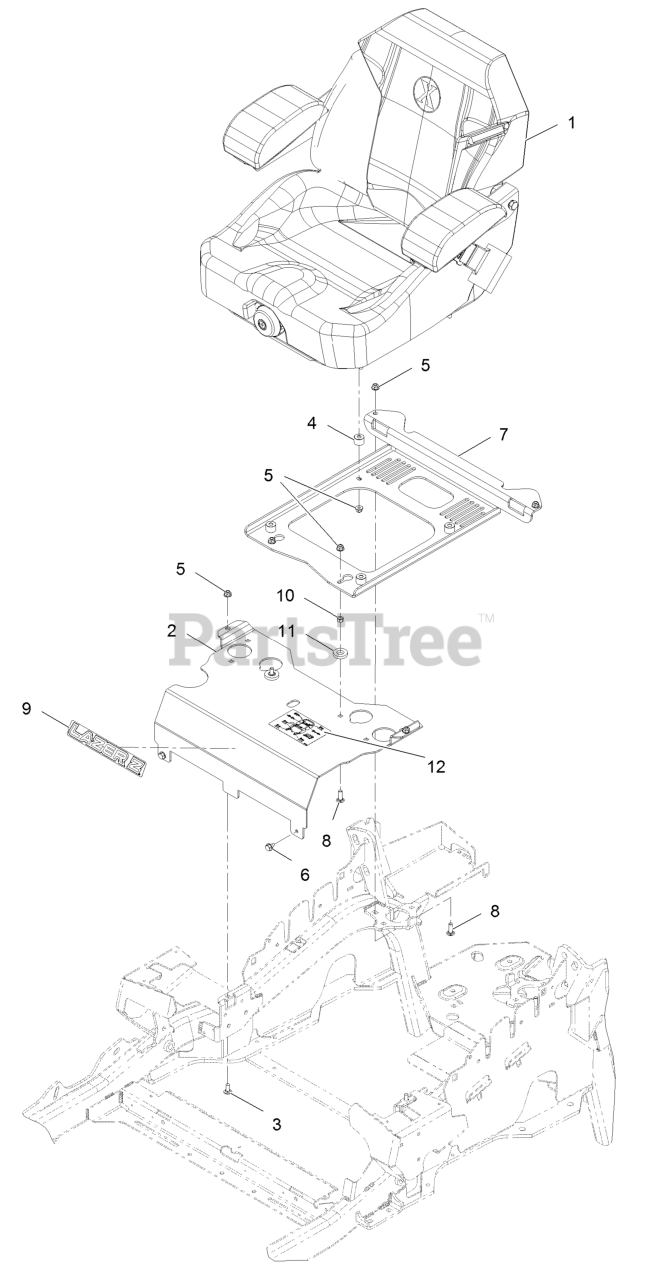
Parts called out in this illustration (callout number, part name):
1	Kit-Suspension Seat
2	Panel-Front, Seat Mount
3	Bolt-Carriage 5/16-18 X 3/4 Short Neck
5	Nut-Nyloc 5/16-18 Flg
6	Screw-HWH 5/16 X 1/2 Tf
7	Plate-Support, Seat
8	Bolt-Carriage 5/16-18 X 1 Sp
9	Decal, Lazer Model
10	Nut-Hex 5/16-18
11	Spacer-Blade Drive
12	Decal-Service Aid
